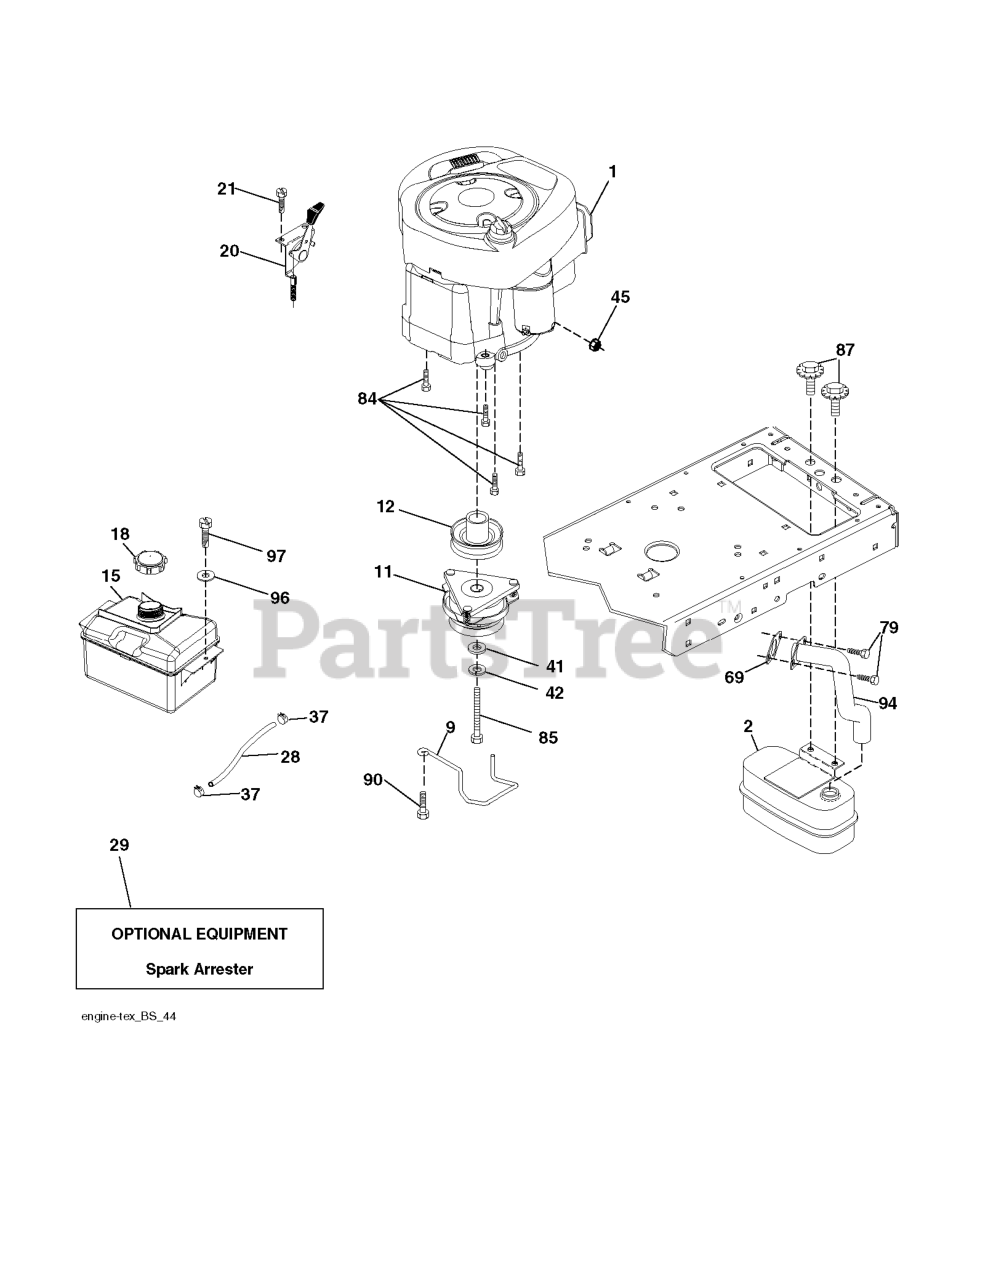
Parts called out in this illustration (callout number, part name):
2	MUFFLER.SINGLE.CYL.KOHL/B&S
9	KEEPER.BELT.ENGINE.4.2
11	RB.CLUTCH.OGURA.4.4.PD
12	PULLEY.ENGINE.TUFFTORQ
15	RP TANK FUEL FRT 1.5 GAL
18	CAP ASM.FUEL.2.25"FR.
20	CONTROL.TH/CK.C.
21	SCREW.#10 X 0.750.BOS
28	LINE.FUEL.20
29	KIT.SPARK ARRESTOR 794945 B&S
37	HOSE CLAMP
42	LOCKWASHER
45	NUT
69	REPL BY 532 27 22-93
79	SCREW.SOCKET HD.5/16-1
84	SCREW.3/8-16
85	BOLT HEX 7/16-20X4-1/4"
87	BOLT.5/16-18UNCX3/4 W/SEMS.BLK
90	SCREW 3/8-16X1
94	EXHAUST.TUBE.B&S.28/31
97	SCREW HEXWSHR 1/4-20X3/4
